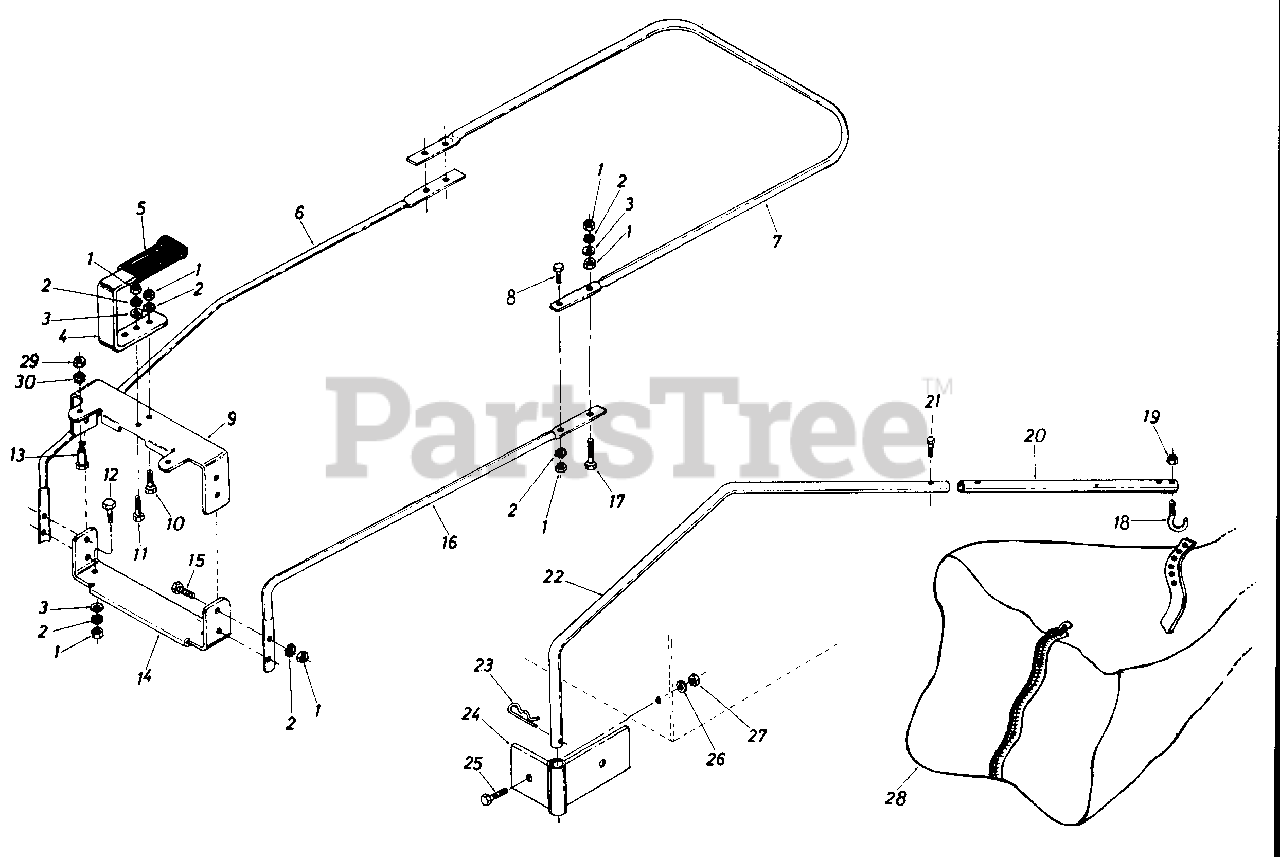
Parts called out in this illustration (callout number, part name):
1	14 Hex Nut 1/4-20 Thd.
2	12 Ext. L.-Wash. 1/4" Scr.
3	Fl.-Wash. .281 I.D. x .50" 0. D.
6	Lower Frame Arm
7	Upper Frame Half
8	Hex Scr. 1/4-20 x 1.00" Lg.
9	Upper Opening Support
10	Hex Scr. 1/4-20 x .62" Lg.
11	Hex Scr. 1/4-20 x .75" Lg.
12	Hex Scr. 1/4-20 x .50" Lg.
13	Shld. Scr. .437" Dia. x .350
14	Lower Opening Support
15	Hex Scr. 1/4-20 x 1.00" Lg;
16	Lower Frame Tubing
17	Hex Scr. 1/4-20 x 1.50" Lg.
19	Hex Ins. L.-Nut 1/4-20 Thd.
22	ILower Holding Arm
23	Internal Cotter Pin 5/8" Dia.
24	Hitch Bracket
25	Hex Sems Scr. 5/16 18 x .75" Lg.
26	L.-Wash. 5/16" Scr.
27	Hex Nut 5/16-18 Thd.
28	Grass Catcher Bag
29	Hex Nut 5/16-18 Thd.
30	Ext. L.-Wash. 5/16" Scr.
